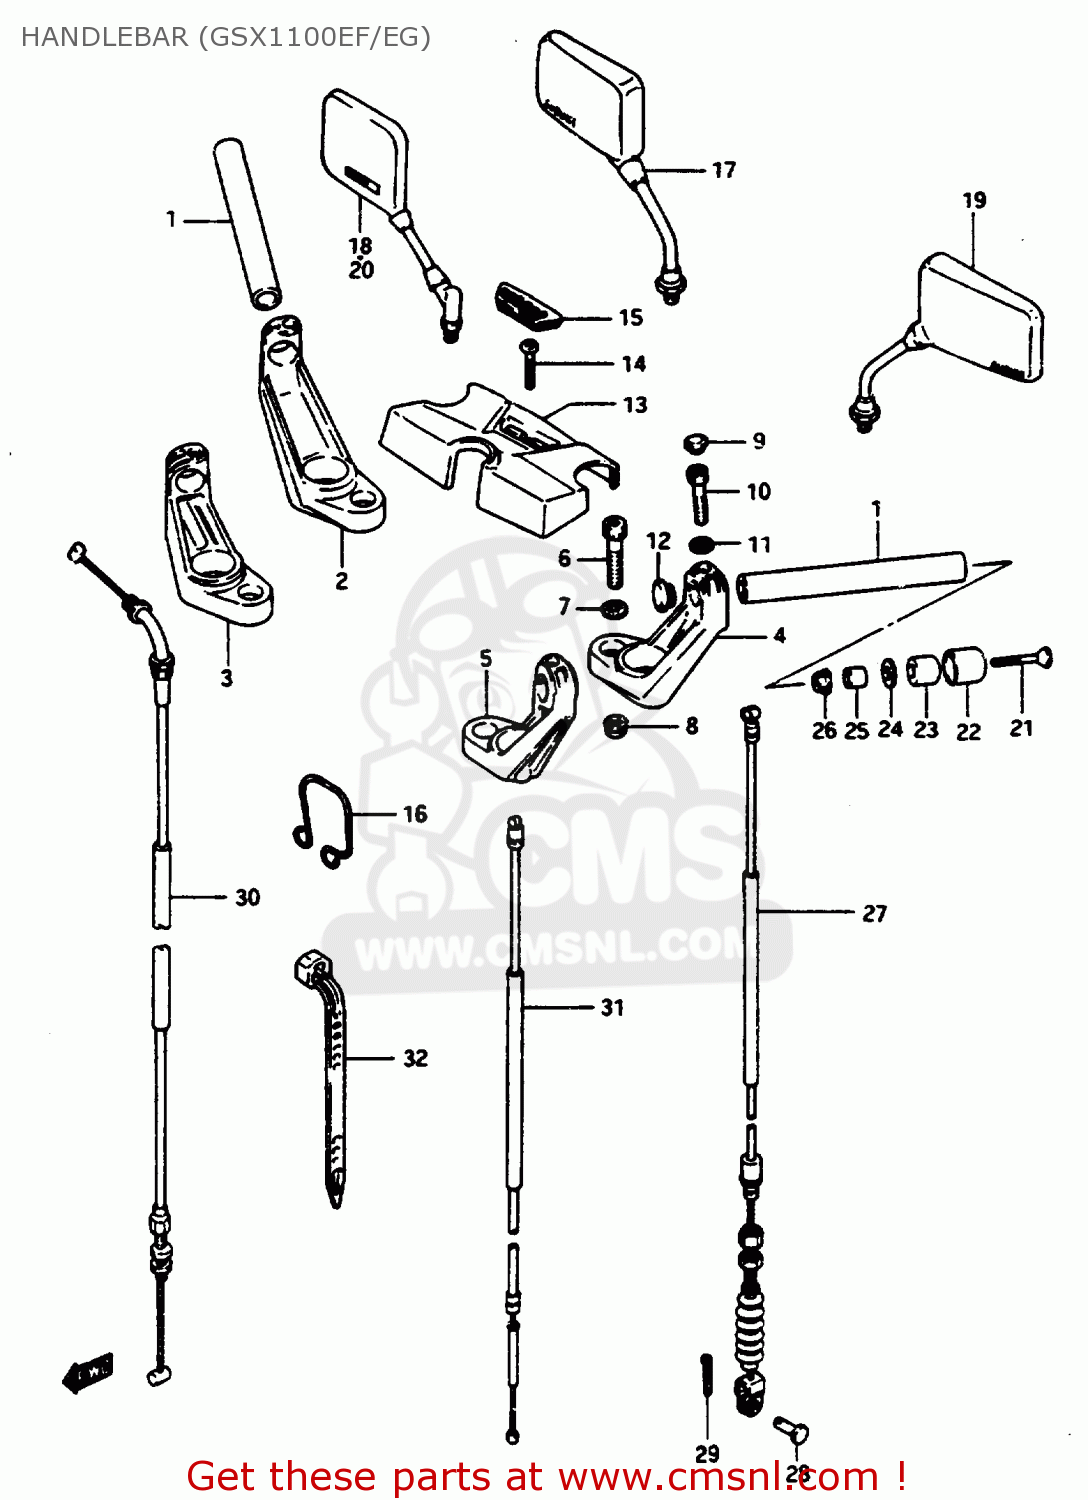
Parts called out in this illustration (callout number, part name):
1	HANDLEBAR
2	HOLDER,HANDLEBAR,RIGHT
3	HOLDER,HANDLEBAR,RIGHT
4	HOLDER,HANDLEBAR,LEFT
5	HOLDER,HANDLEBAR,LEFT
6	BOLT(10X50)
7	WASHER
8	NUT 10MM
9	CAP(OD:14.5)
10	BOLT 8X35
11	WASHER
12	CAP,GRIP END
13	PAD,HANDLE
14	SCREW
15	CAP,HANDLE PAD
16	GUIDE,CABLE/HARNESS
17	MIRROR, REAR VIEW RH
18	MIRROR ASSEMBLY,REAR VIEW
19	MIRROR, REAR VIEW LH
20	MIRROR ASSEMBLY,REAR VIEW
21	SCREW 6X55
22	CAP,BALANCER
23	BALANCER,HANDLEBAR
24	SPACER,BALANCER
25	EXPANDER,BALANCER
26	NUT
27	CABLE ASSY,CLUTCH
28	PIN(L:15)
29	PIN
30	CABLE ASSY,THROTTLE
31	CABLE COMP,STARTER
32	CLAMP(L:165)
